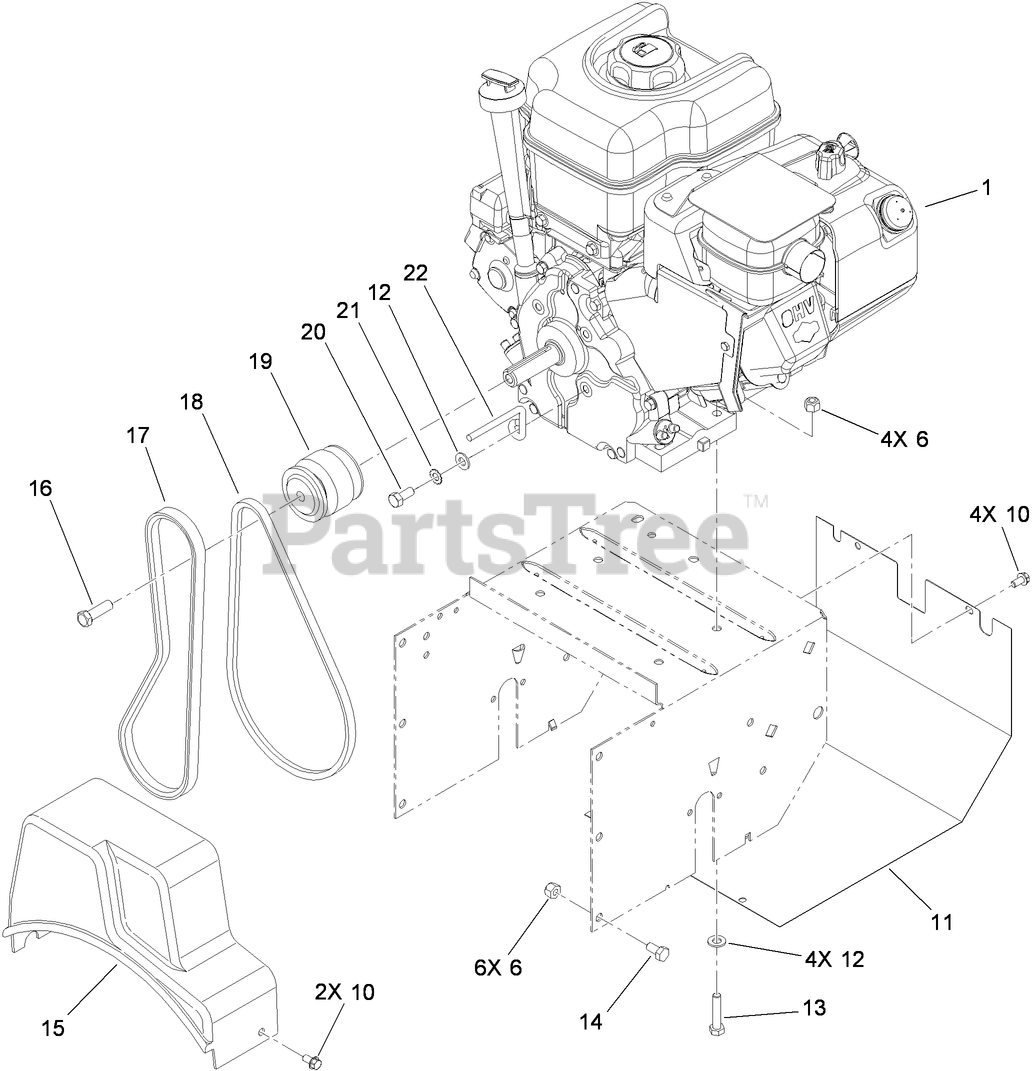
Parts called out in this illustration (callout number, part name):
6	NUT-LOCK, NI
10	SCREW-HWH
11	COVER-TRACTION, LOWER
12	WASHER-PLAIN
13	SCREW-HH
14	SCREW-HH
15	COVER-BELT
16	SCREW-SPECIAL
17	V-BELT
18	V BELT-3L, TRACTION
19	PULLEY-ENGINE
20	SCREW-HH
21	WASHER-LOCK
22	RETAINER-BELT
